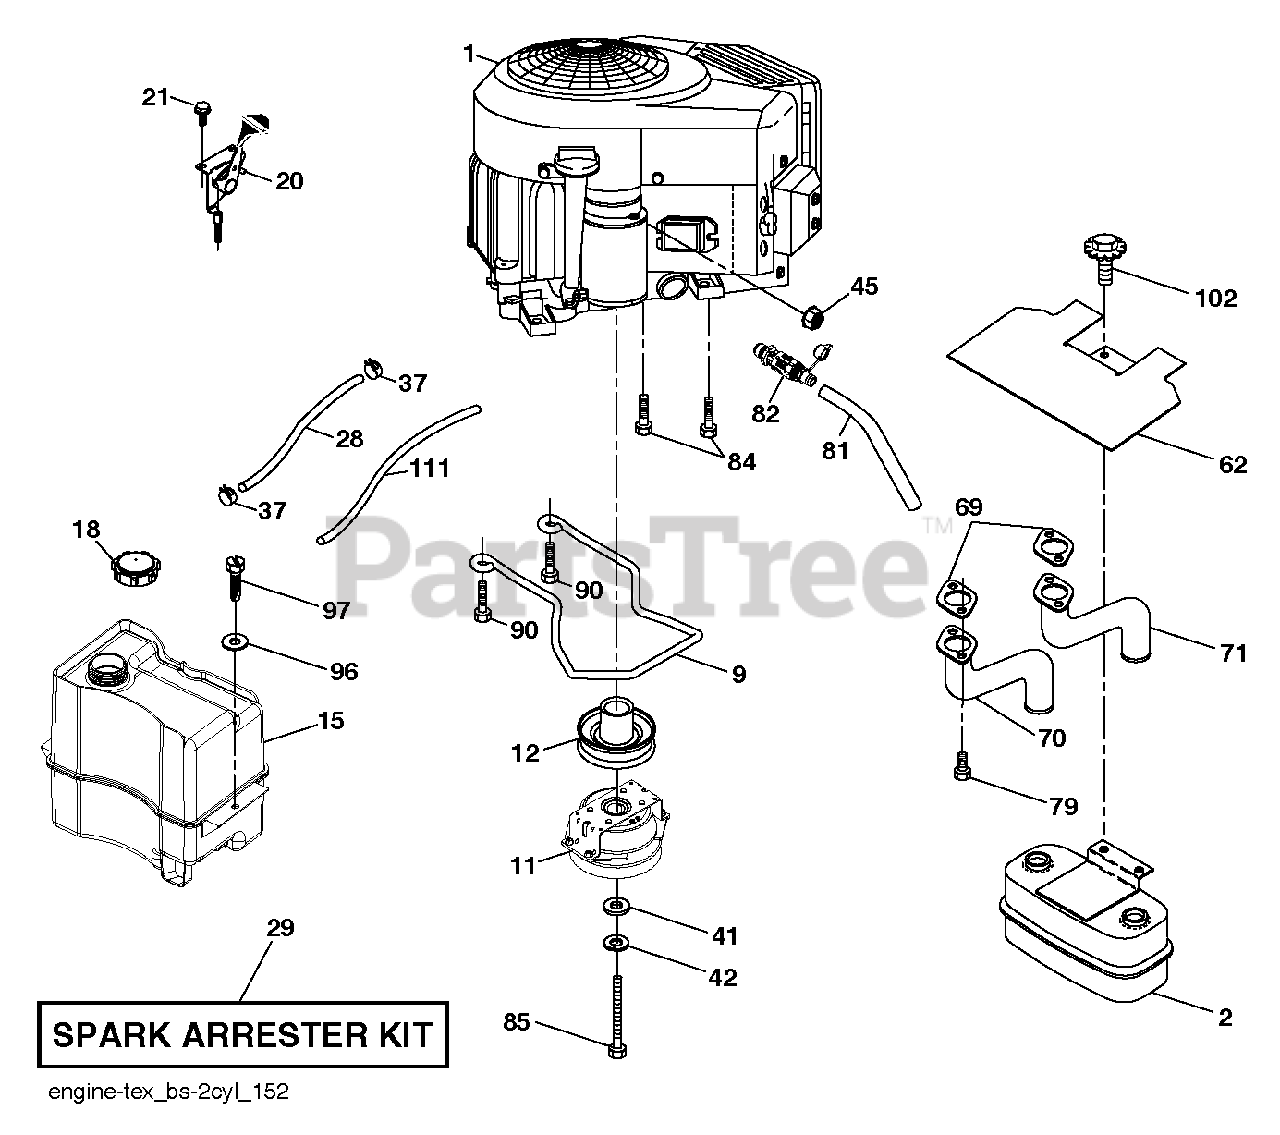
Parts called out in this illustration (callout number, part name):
2	MUFFLER.ASM.TWN.EXTNDED.DFLCTR
9	KEEPER.BELT.ENG.4.25"2.BLT.431
11	Clutch, Ogura 5.0Pd Gt1.5A-Eh07
12	PULLEY.ENGINE.TUFFTORQ
15	TANK.ASM.FRT.2.5 GAL.W/CAP.EPA
18	CAP.FUEL.2 WAY VENT
20	Throttle, Cobra 38" Readstart.Bk
21	SCREW.#10 X 0.750.BOS (2 2)
28	LINE.FUEL.20"FRONT.EMI
29	SPARK ARRESTOR KIT
37	HOSE CLAMP
42	LOCKWASHER
45	NUT
62	SHIELD.HEAT.MUFFLER
69	GASKET.MUFFLER
70	EXHAUST.TUBE.LH.BS/TWIN
71	EXHAUST.TUBE.RH.B&S.TWIN.INTEK
79	SCREW.SOCKET.HEAD.5/16-18
81	TUBE, DRAIN OIL ASM.
82	VALUE.OIL.DRAIN
84	SCREW.3/8-16
85	BOLT HEX 7/16-20 X 3.75 GR. 5
90	SCREW 3/8-16X1
97	SCREW HEXWSHR 1/4-20X3/4
102	SCREW
111	RP PURGE LINE
